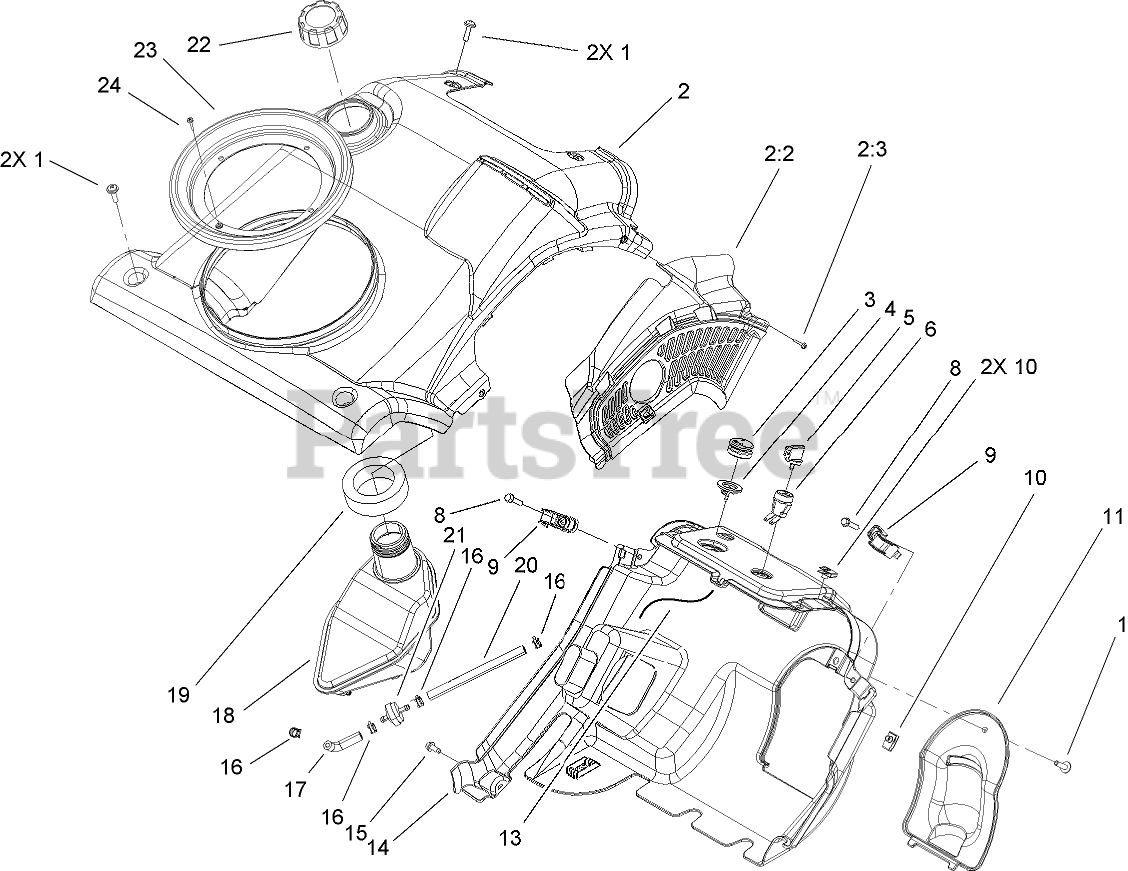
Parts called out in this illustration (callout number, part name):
1	SCREW-PPH
2	SHROUD ASM
2:2	BAFFLE-HEAT
2:3	SCREW-PPH
3	BULB-PRIMER
4	BODY-PRIMER
5	KEY-IGNITION
6	SWITCH
8	SCREW-PLASTITE
9	CLIP-SHROUD
11	PANEL-ACCESS, CARBURETOR
13	HOSE-PRIMER
14	SHROUD-LOWER
15	SCREW-HWH
16	CLAMP-HOSE
17	HOSE-FUEL
18	TANK-GAS
19	SEAL-TANK
20	HOSE-FUEL
21	FILTER-FUEL
22	GAS CAP ASM
23	SEAL-RING, CHUTE
24	SCREW-PPH
